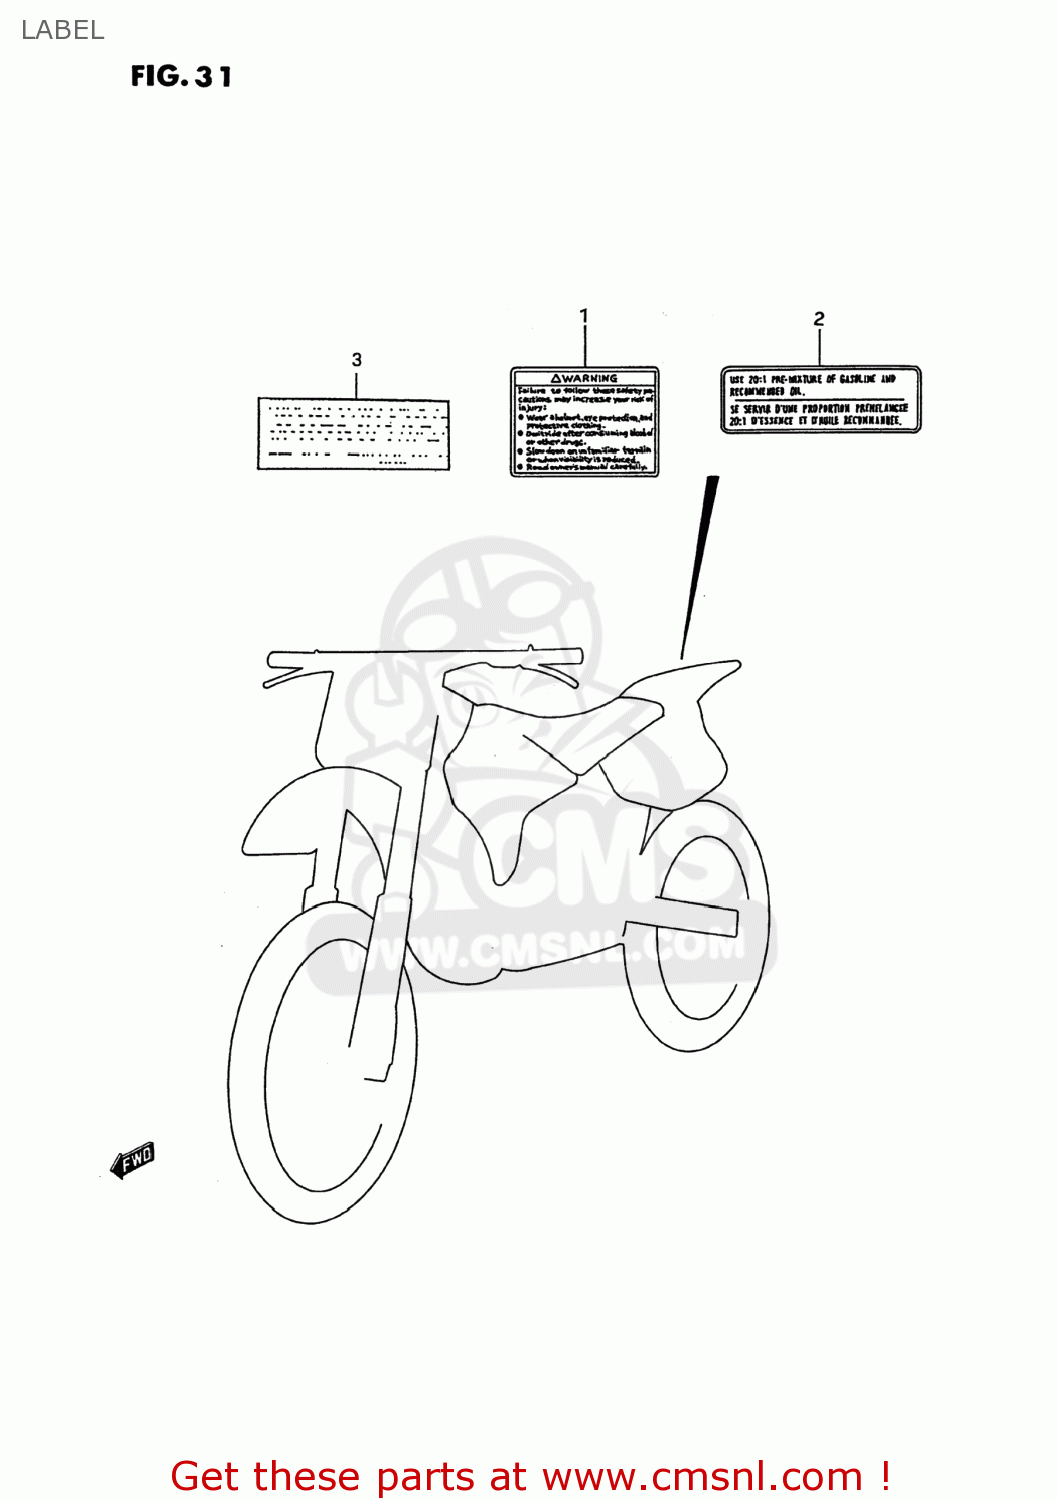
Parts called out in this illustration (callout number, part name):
1	LABEL
2	LABEL,WARNING
3	LABEL (MANUAL NOTICE)
4	OM RMX250
